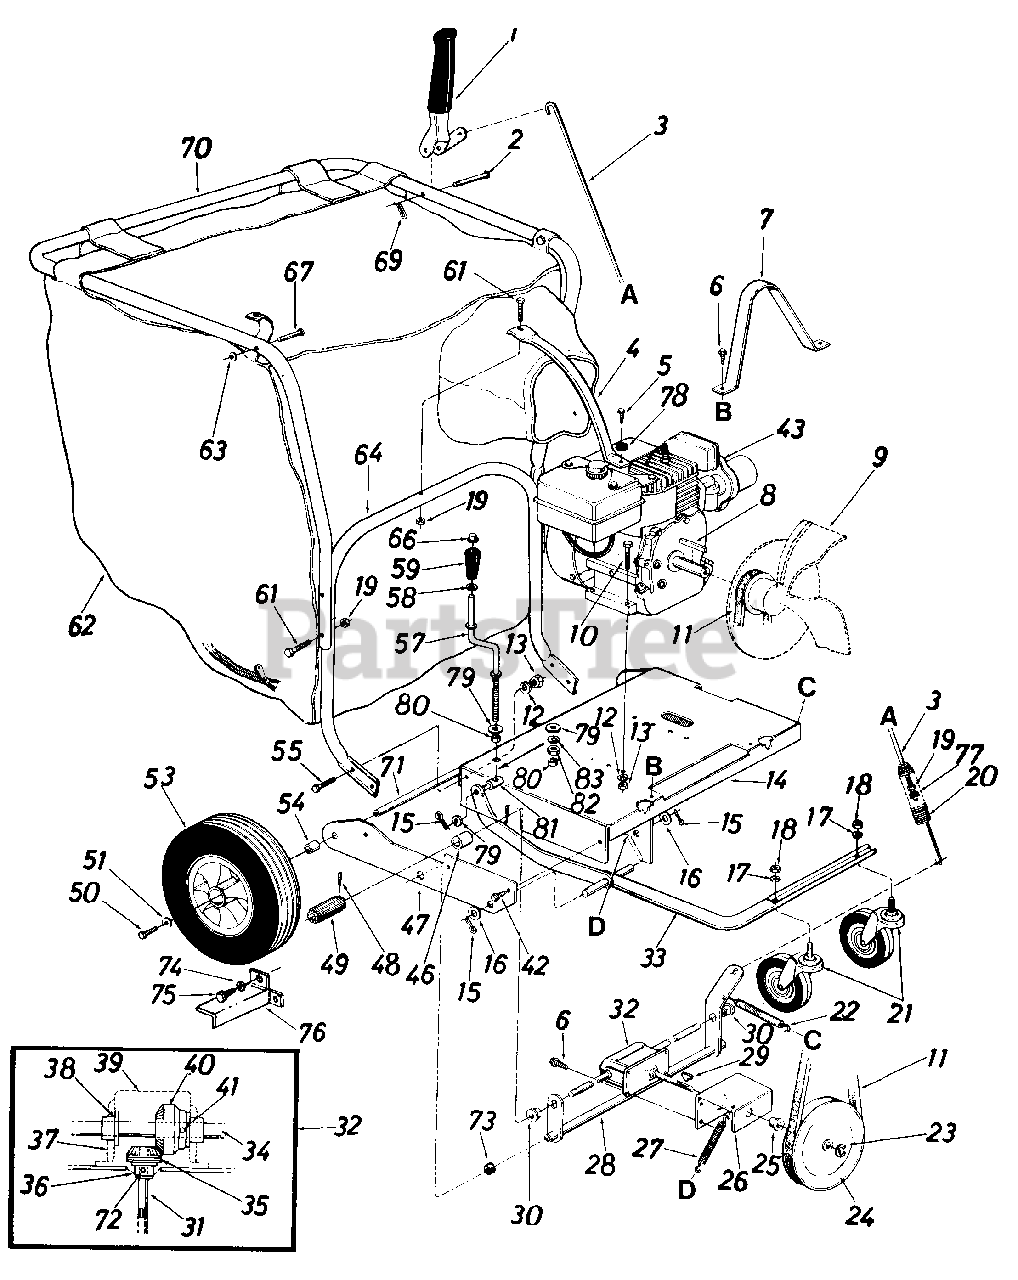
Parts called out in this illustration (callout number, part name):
1	Clutch Grip Ass'y
2	Clevis Pin .375" Dia. x 1.88"
3	Clutch Rod 32" Lg.
4	Handle Brace (Painted)
5	Part of Engine
6	Hex Wash. Hd. AB-Tap Scr. 1/4" x.62" Lg.
11	'V-Belt
12	L-Wash. 5/16" I.D.
13	Hex Nut 5/16-18 Thd.
16	Fl-Wash. .63" I.D. x 1.25" O.D.
17	L-Wash. 1/2" I.D.
18	Hex Nut 1/2-13 Thd.
19	Hex Cent. L-Nut 1/4-20 Thd.
20	Extension Spring .78" O.D. x .75" Lg.
21	Swivel Caster Wheel 5" Dia. x 1 .25"
22	Extension Spring .38" O.D. x 7 50" Lg.
23	Snap "E"-Ring.50" Dia. Shaft
24	"V"-Pulley 5/8" x 6.50" O.D.
25	Flange Bearing .502" I.D.
28	Clutch Bracket Ass'y.
29	#2 Woodruff Key 3/32" Dia. x .81 " Lg.
30	Hex Flange Bearing Bronze .625" I.D.
31	Pinion Shaft .50" Dia. x 5"
32	Gear Box Ass y. Comp.
35	Bevel Gear .50" I.D. x 14 Teeth
36	Flange Bearing .503" I.D.
37	Gear Box
38	Flange Bearing .630" I.D.
39	Gear Box Cover
40	Bevel Gear .62" I.D. x 28 Teeth
41	Spring Pin Spiral 3/16" Dia. x 1.25" Lg.
42	Hex Wash. Hd. AB-Tap Scr. 5/16" x .75" Lg.
43	Engine
46	Spacer .63" I.D. x .88" O.D. x .56" Lg.
49	Drive Pinion
50	Hex Locking Bolt 5/16-24 x .62" Lg.
51	Fl-Wash. .34" I.D. x .87" O.D.
53	Wheel Ass'y. Comp. 12" x 3" (Incl. Ball Bearings)
54	Spacer .63" I.D. x 1.0" O.D. x .94" Lg.
55	Hex Bolt 5/16-18 x .75" Lg.
57	Height Adjustment Crank
58	Fl-Wash. .385" I.D. x .62" O.D.
59	Crank Knob
61	Hex Bolt 1/4-20 x 1.75" Lg.
62	Vacuum Bag Felt
63	Push Speed Nut .25" Dia. Stud
66	Push Nut 3/8" Dia.
67	Stud Pin .250" Dia. x 1.75"
69	Internal Cotter Pin 3/8" Dia.
70	Upper Handle (Painted)
71	Rear Axle
72	Spring Roll Pin 5/32" Dia. x 1 .12
73	Spacer .82" I.D. x 1.0" O.D. x .305 Lg.
74	L-Wash. .265" I.D.
75	Hex Self-Tap Scr. 1/4" x 3/8" Lg.
78	Belleville Washer
79	Fl-Wash. .35" I.D. x .87" O.D.
80	Spacer .38" I.D. x .50" O.D. x .18" Lg.
81	Ferrule 3/8-8 x .38" Dia.
82	Hex Nut 3/8-8 Thd.
83	L-Wash. 3/8" I.D.
14530-0498	PLATE-SIDE-RH - OLD CUB YELLOW (0498)
14530-0499	PLATE-SIDE-RH - CUB BEIGE (0499)
14530-0637	PLATE-SIDE-RH - POWDER BLACK (0637)
14530-0638	PLATE-SIDE-RH - MTD/TROY-BILT RED (0638)
16273-0498	Double Caster Arm Assembly, Black - OLD CUB YELLOW (0498)
16273-0637	Double Caster Arm Assembly, Black - POWDER BLACK (0637)
16273-0638	Double Caster Arm Assembly, Black - MTD/TROY-BILT RED (0638)
16273-0648	Double Caster Arm Assembly, Black - TECH GRAY (0648)
16273-0662	Double Caster Arm Assembly, Black - OYSTER GRAY (0662)
16273-0674	Double Caster Arm Assembly, Black - YARDMAN YELLOW (0674)
16273-0691	Double Caster Arm Assembly, Black - BLACK JACK (0691)
16273-0709	Double Caster Arm Assembly, Black - MASTERCRAFT GREEN (0709)
